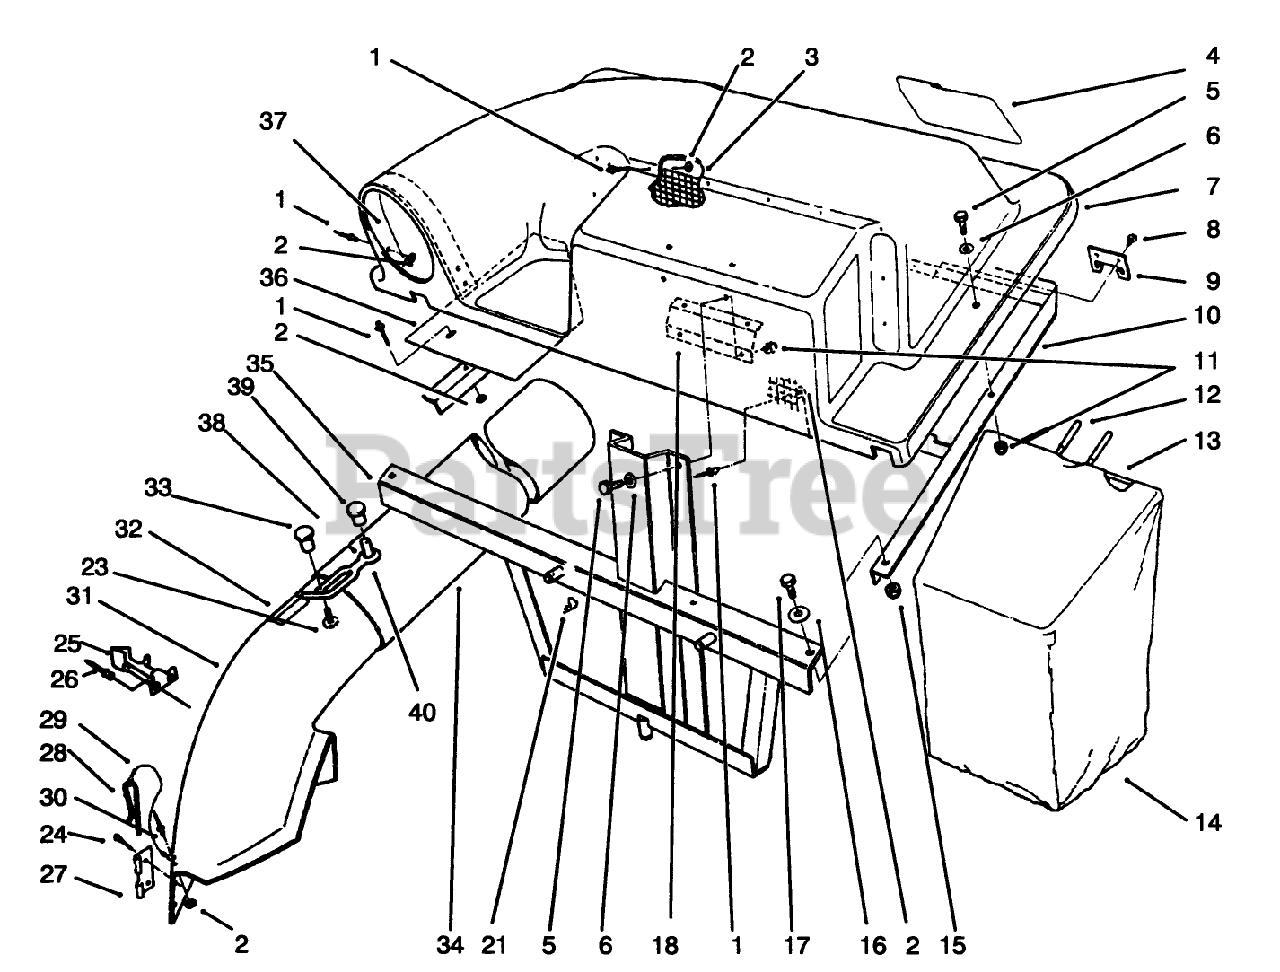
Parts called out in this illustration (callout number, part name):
1	RIVET-POP
2	WASHER-PLAIN
3	SCREEN
4	DECAL-BAGGER, TWIN
5	SCREW-HH
6	WASHER-PLAIN
7	COVER-BAGGER, TWIN
8	SCREW-HWH
9	BRACKET-FRAME, BAG
10	Cover-Frame
11	NUT-LOCK, NI
12	GRIP-HANDLE, BAG
13	Frame-Bag
15	NUT-LOCK, NI
16	WASHER-FLAT
17	SCREW-HH
18	Plate-Backup
21	PIN-HAIR
23	SCREW-PPHTF
24	RIVET-BLIND
25	Latch-38"
26	RIVET-POP
27	BRACKET-MOUNTING, CHUTE
28	PIN-LOCKING, CHUTE
29	LANYARD
30	RIVET-BLIND
31	CHUTE
32	DECAL-DANGER
34	GRASS DISCHARGE TUBE
35	Frame-Mounting
36	Baffle
37	Support Inlet
38	SPACER-INTERLOCK
39	FASTENER-PANEL
40	RETAINER-DUCT
